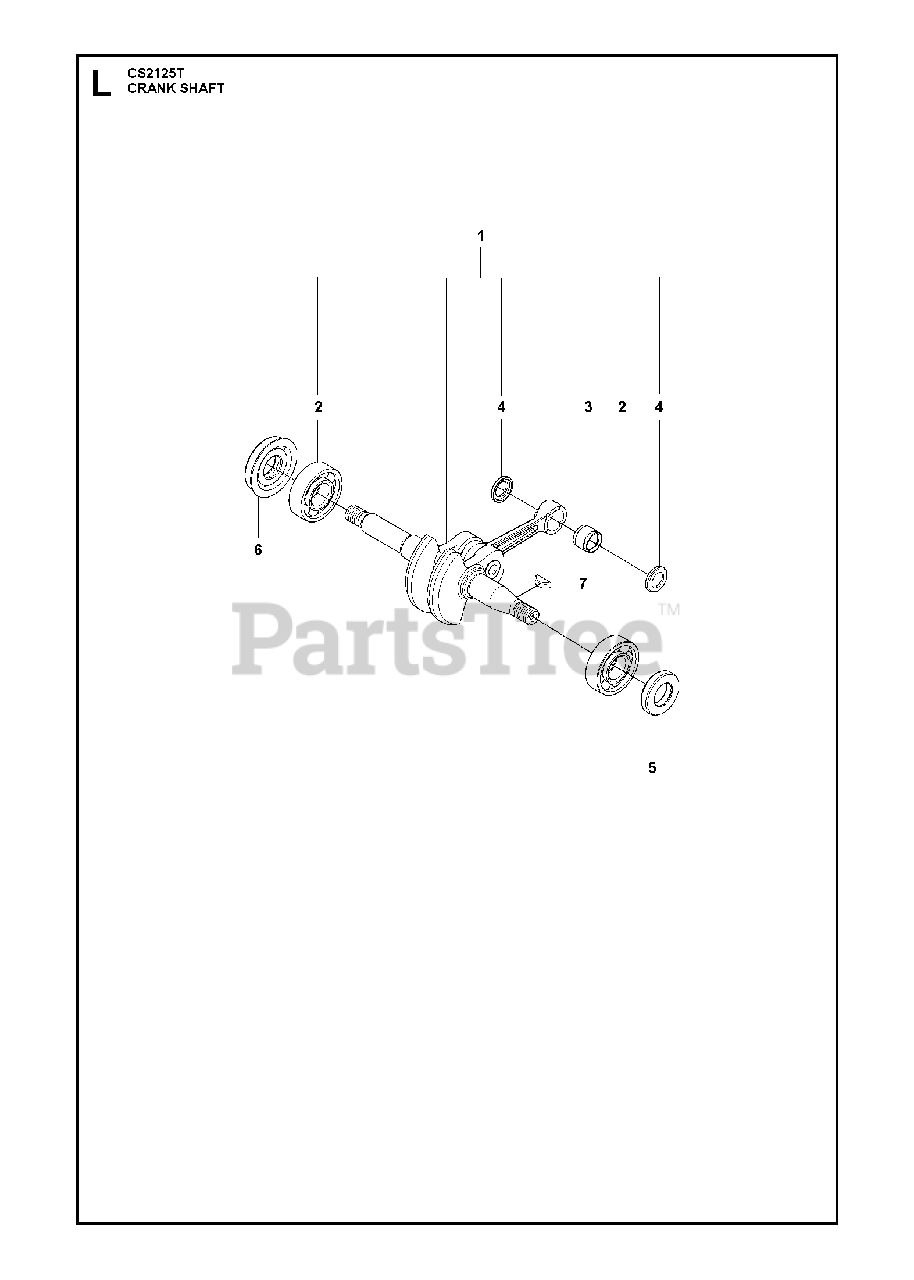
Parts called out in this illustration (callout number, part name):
3	BEARING
4	WASHER
7	KEY
